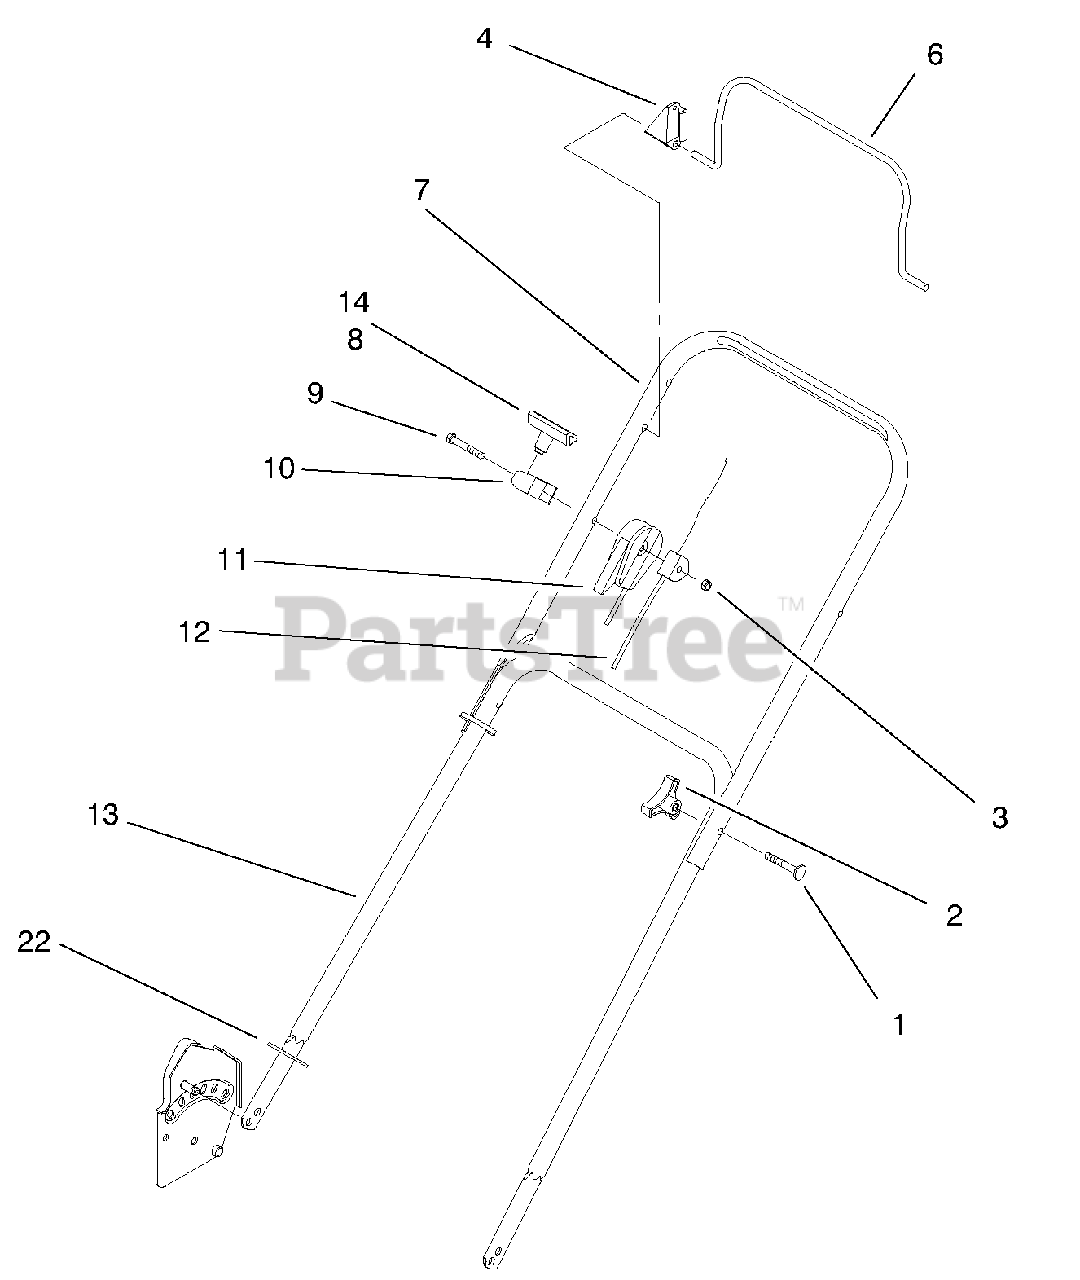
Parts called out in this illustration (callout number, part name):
1	Screw-Handle
2	Knob
3	Nut-Lock
4	Stop-Pivot
6	Bail-Flywheel Brake
7	Handle Section-Upper
8	Handle-Starter
9	Screw-HH
10	Guide-Rope
11	Cable-Throttle
12	ASM-Brake Cable
13	Handle Section-Lower
14	Staple-Handle
22	Handle-Guard
